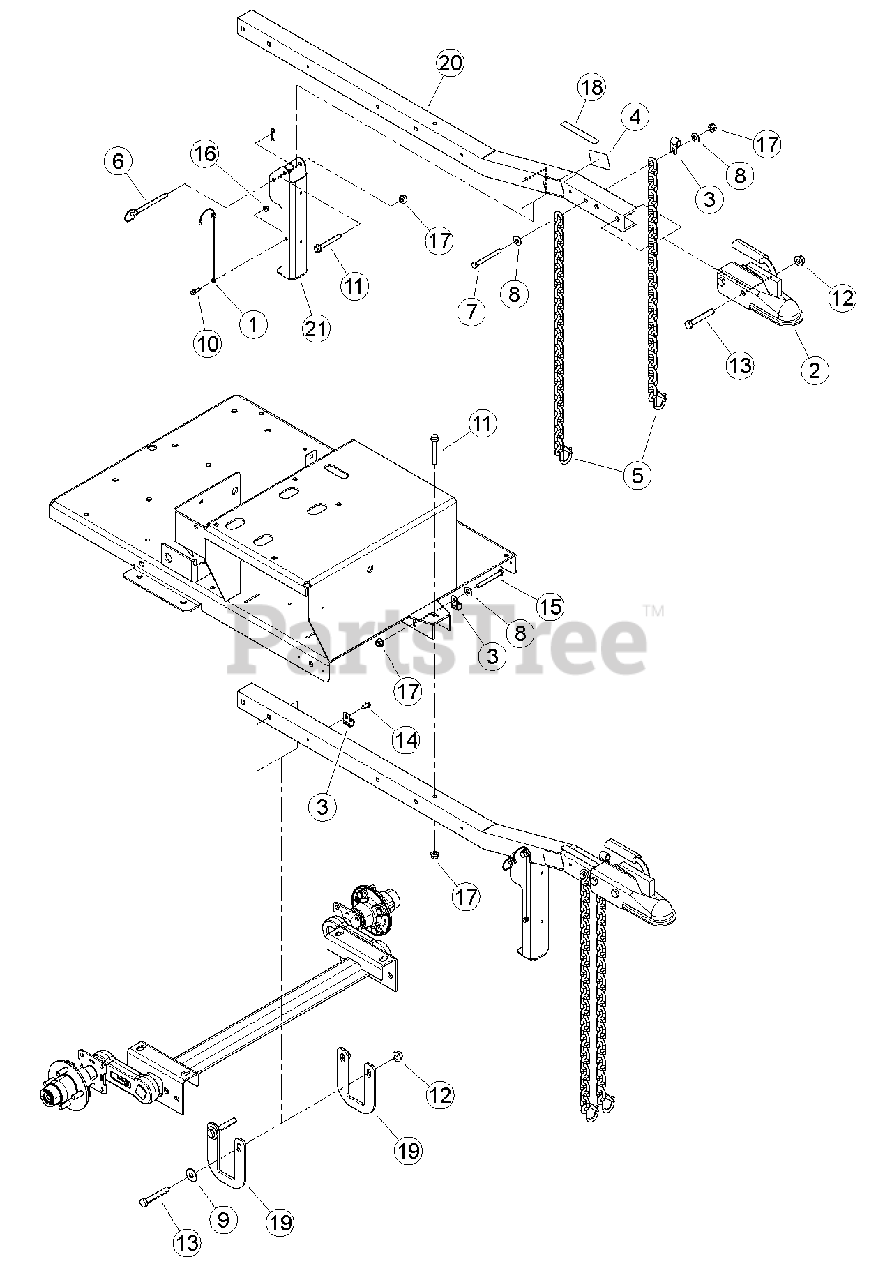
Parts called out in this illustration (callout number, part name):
1	LANYARD, NYLON
2	COUPLER, 50 MM BALL
3	CLAMP, 9/16 COATED
4	REFLECTOR, WIDE ANGLE AMBER
5	CHAIN, SAFETY 5000 LB W/ LATCH
6	PIN, 3/8 HITCH
7	BOLT, 3/8 X 3-1/2" HEX HD GR5 ZP
8	WASHER, 3/8 FLAT
9	WASHER, 1/2 FLAT
10	BOLT, 1/4-20 X 3/4 HWH GR5 CZP
11	BOLT, 3/8 X 3 FLANGE NC
12	NUT, 1/2-13 NYLOCK FLANGE
13	BOLT, 1/2 X 3-1/4 HCS GR5 ZP
14	SCREW, 11/32-12 X 7/8 HWH T-AB
15	BOLT, 3/8 X 3-1/4 HEX HD GR5 ZP
16	NUT, 1/4-20 NYLOCK FLANGE
17	NUT, 3/8-16 NYLOCK FLANGE
18	DECAL, HITCH LOAD
19	PLATE, HITCH SADDLE
20	POLE, C/S HITCH
21	WELDMENT, STAND JACK
